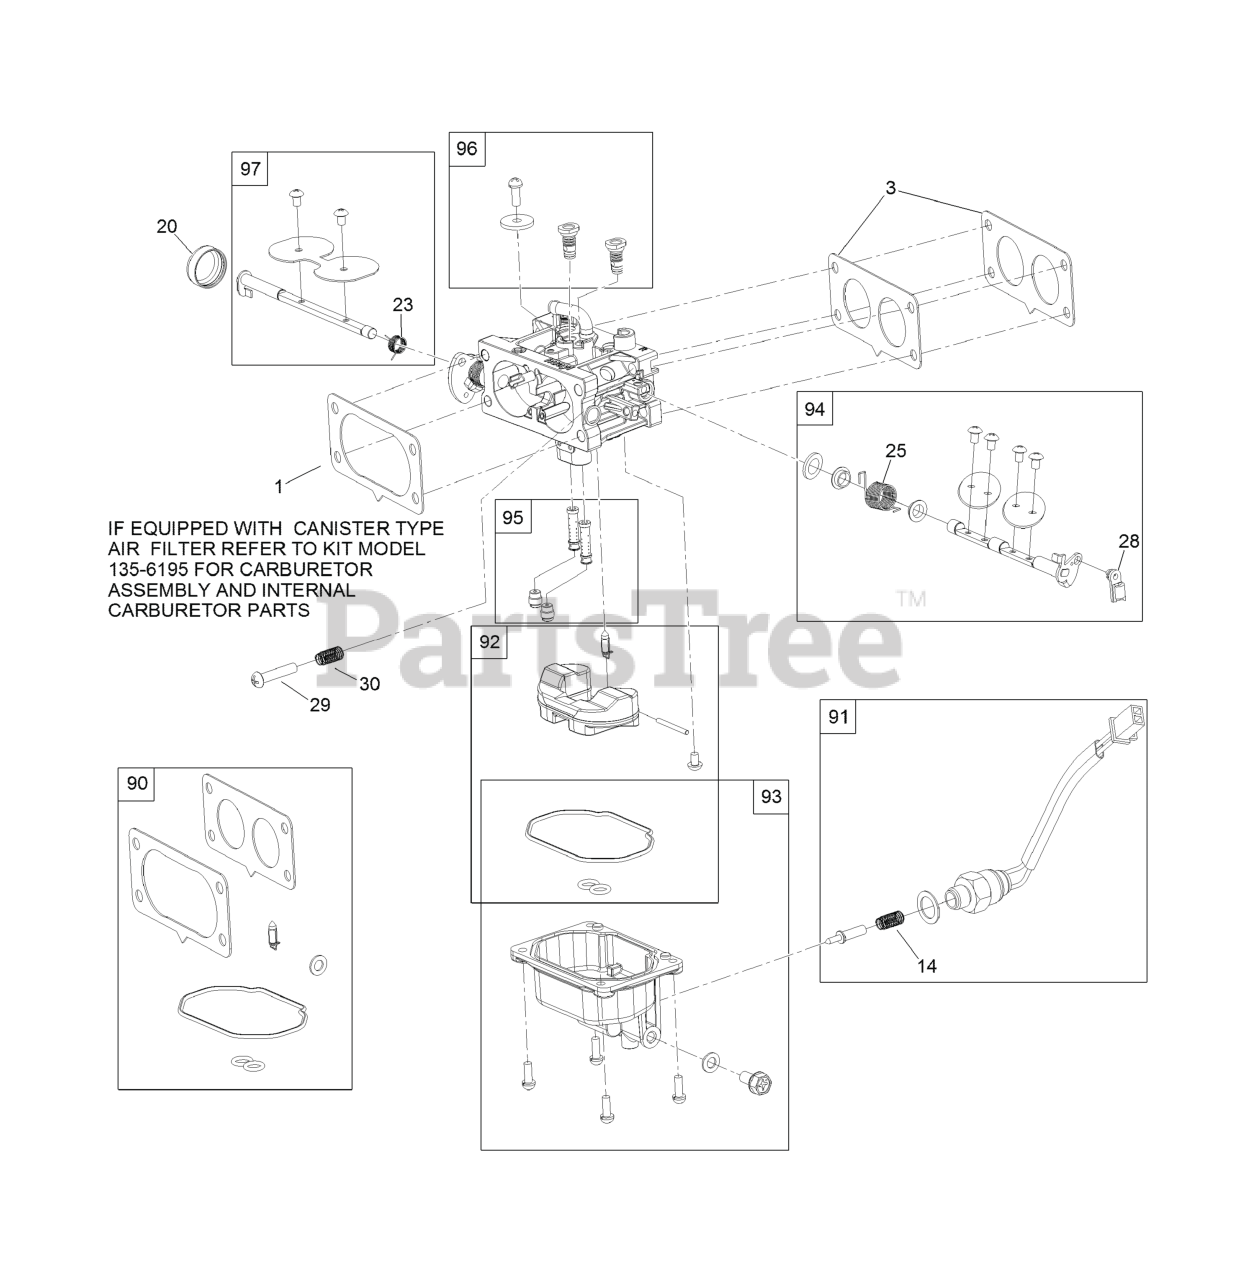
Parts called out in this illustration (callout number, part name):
1	GASKET-CARBURETOR
3	GASKET-CARBURETOR
20	COVER-SHAFT, CHOKE
28	CLAMP-LOCK
29	SCREW-PPH
90	CARBURETOR REPAIR KIT
91	SOLENOID KIT
92	FLOAT KIT
93	BOWL KIT
94	THROTTLE SHAFT KIT
95	NOZZLE AND JET KIT
96	IDLE JET KIT
97	CHOKE SHAFT KIT
